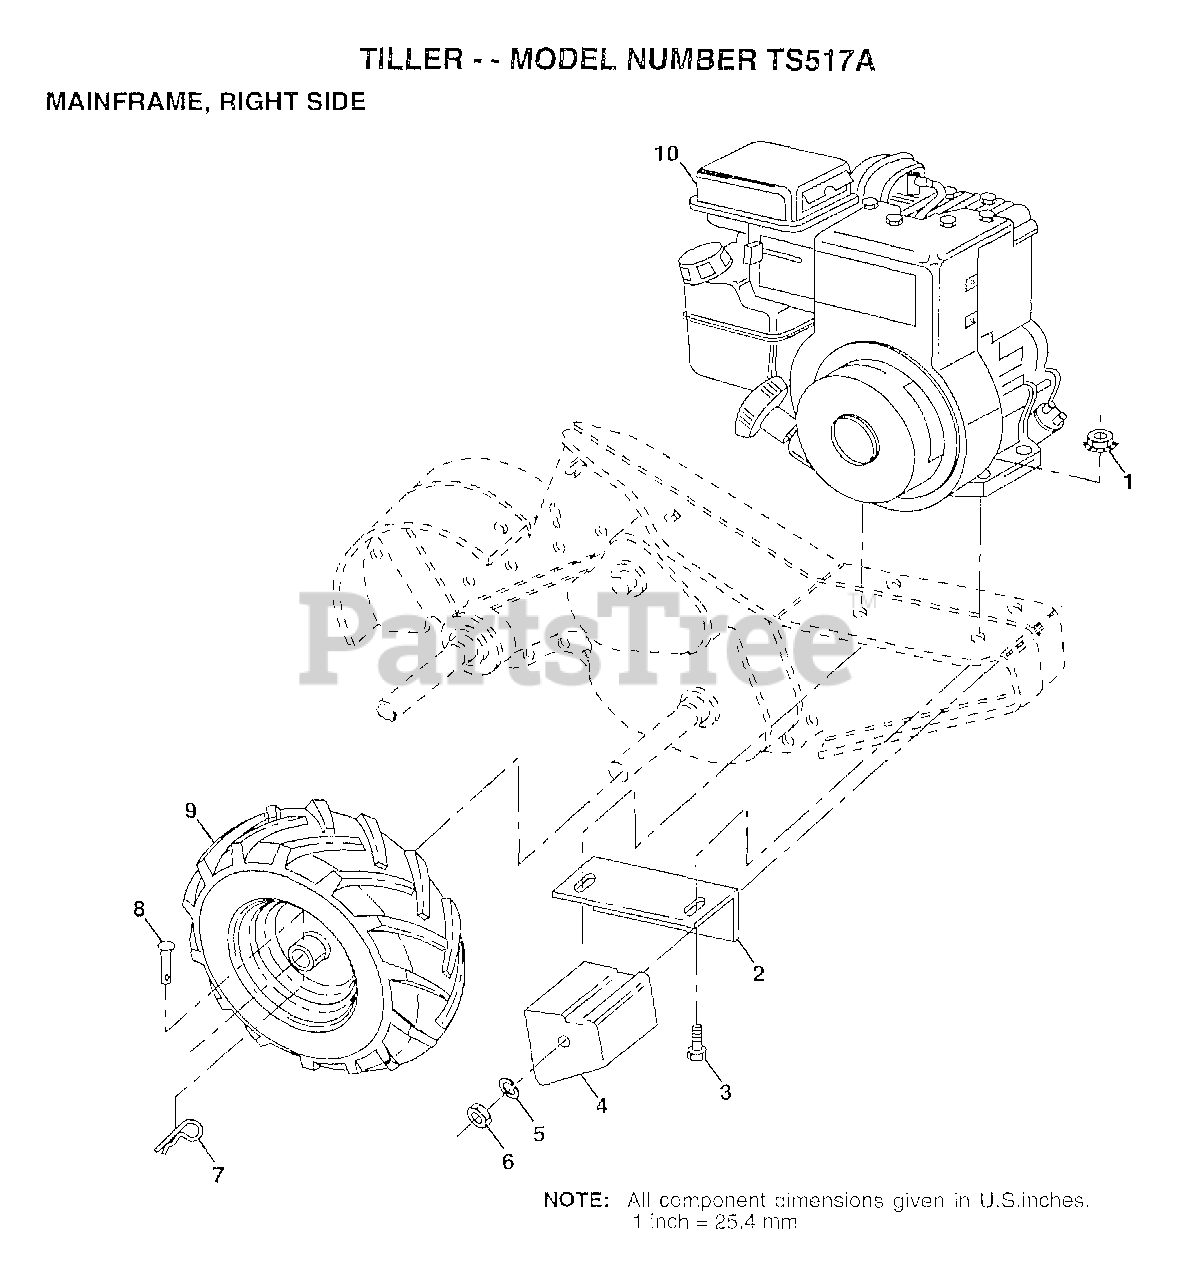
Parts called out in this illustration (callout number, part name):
2	BRACKET RH CRT
3	BOLT.HEX.5/16-1.5
4	COUNTERWEIGHT CRT
5	LOCKWASHER
6	NUT.HEX.3/8-16UNC
7	RETAINER M
8	RIVET.DRILL.1.75
9	TIRE.CHV.13X5.0-6
